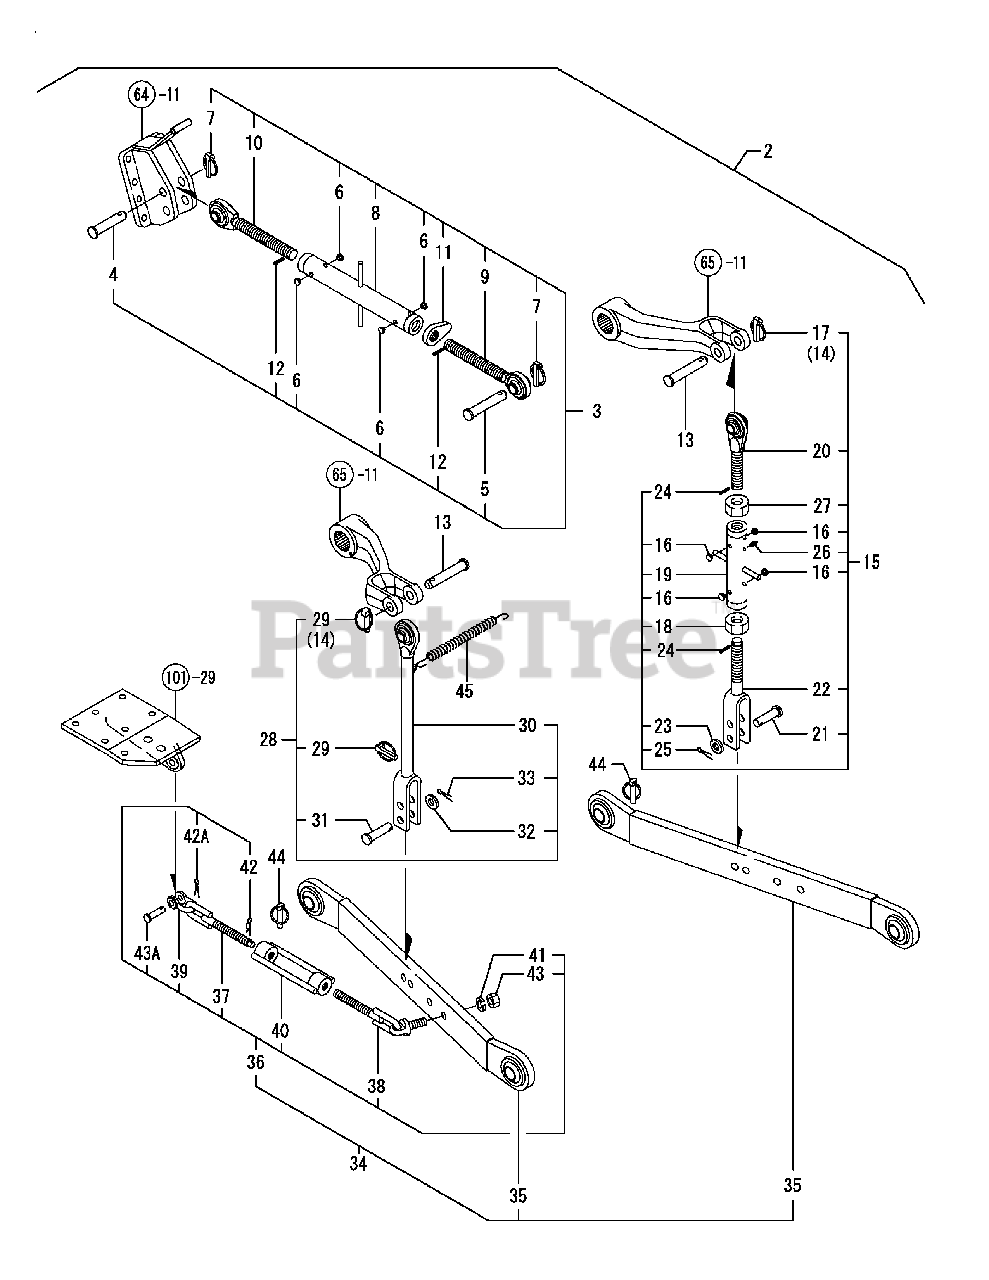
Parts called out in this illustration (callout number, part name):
7	LYNCH PIN ASSLY
12	SPRING PIN 5X25
14	LYNCH PIN ASSLY
15	ADJ.LIFT ROD ASSY
17	LYNCH PIN ASSLY
22	LOWER END ASSY
23	WASHER 16,POLISHED
24	SPRING PIN 5X22
25	COTTER PIN 3.2X32
26	NIPPLE MT6X1, GREASE
27	LOCK NUT M24 PLATED
28	FIXED LIFT ROD ASSY
29	LYNCH PIN ASSLY
30	LINK ASSY, LIFT L.H.
32	WASHER 16,POLISHED
33	COTTER PIN 3.2X32
34	LINK & CHAIN KIT,
35	LOWER LINK ASSY
36	CHAIN STAB, ASSY
37	CHAIN ASSY,FRONT
38	CHAIN ASSY,REAR
41	SPRING WASHER 16
44	PIN ASSY,BALL SOCKET
